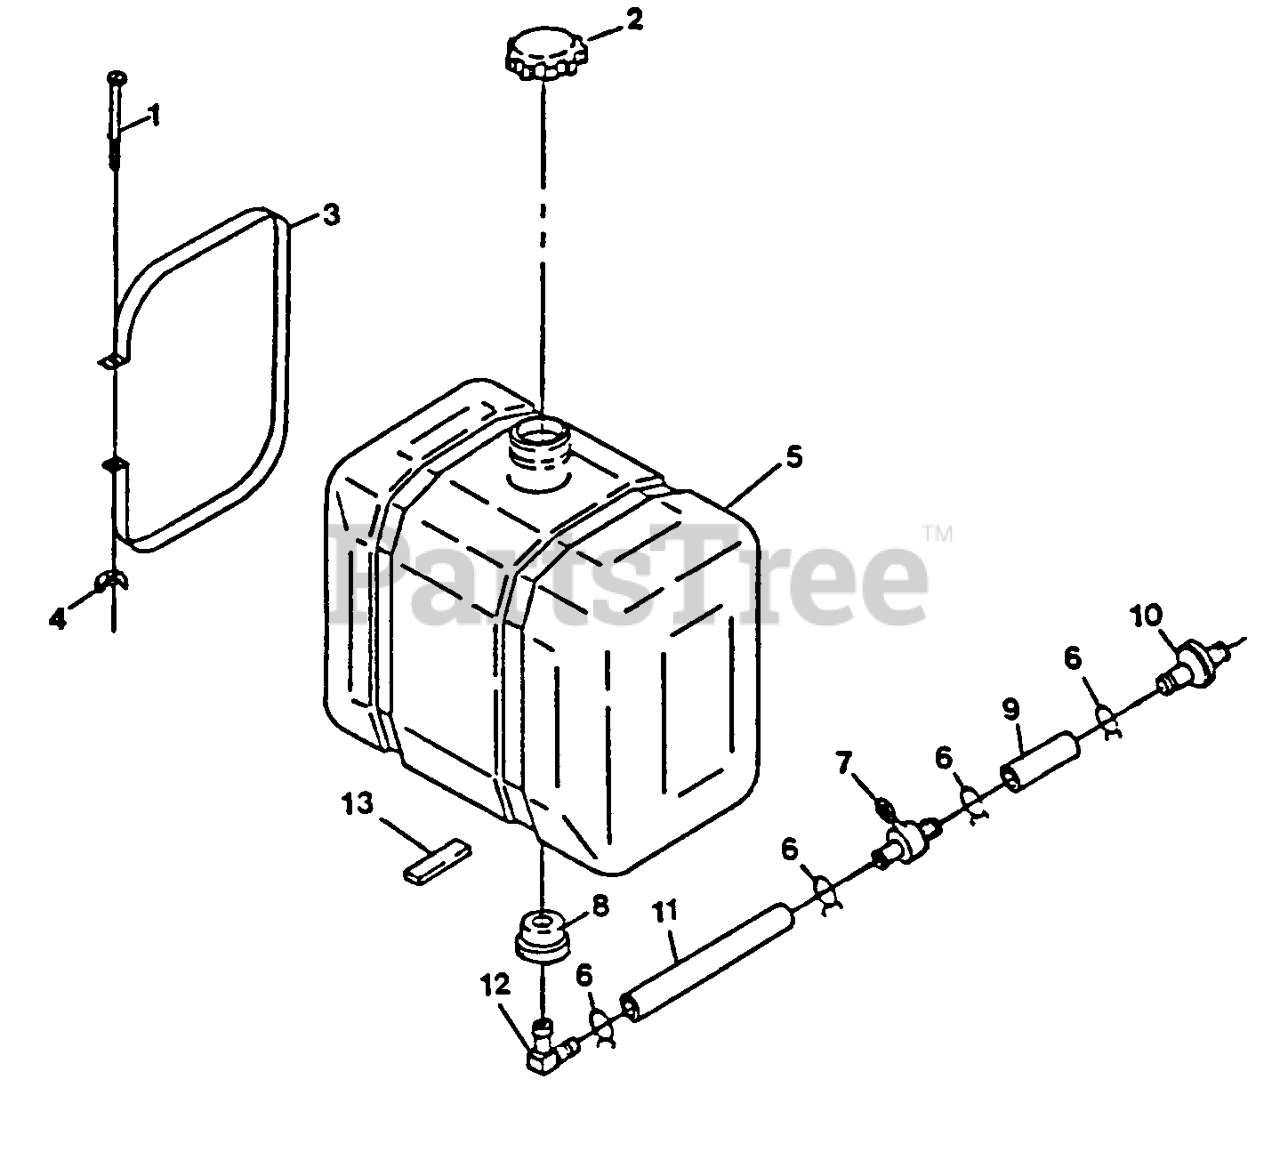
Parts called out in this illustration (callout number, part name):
1	SCRW,MACH CRPH
2	CAP-FUEL
4	WINGNUT
7	VALVE-FUEL
9	HOSE-LINE, FUEL
12	ELBOW-TANK, FUEL
